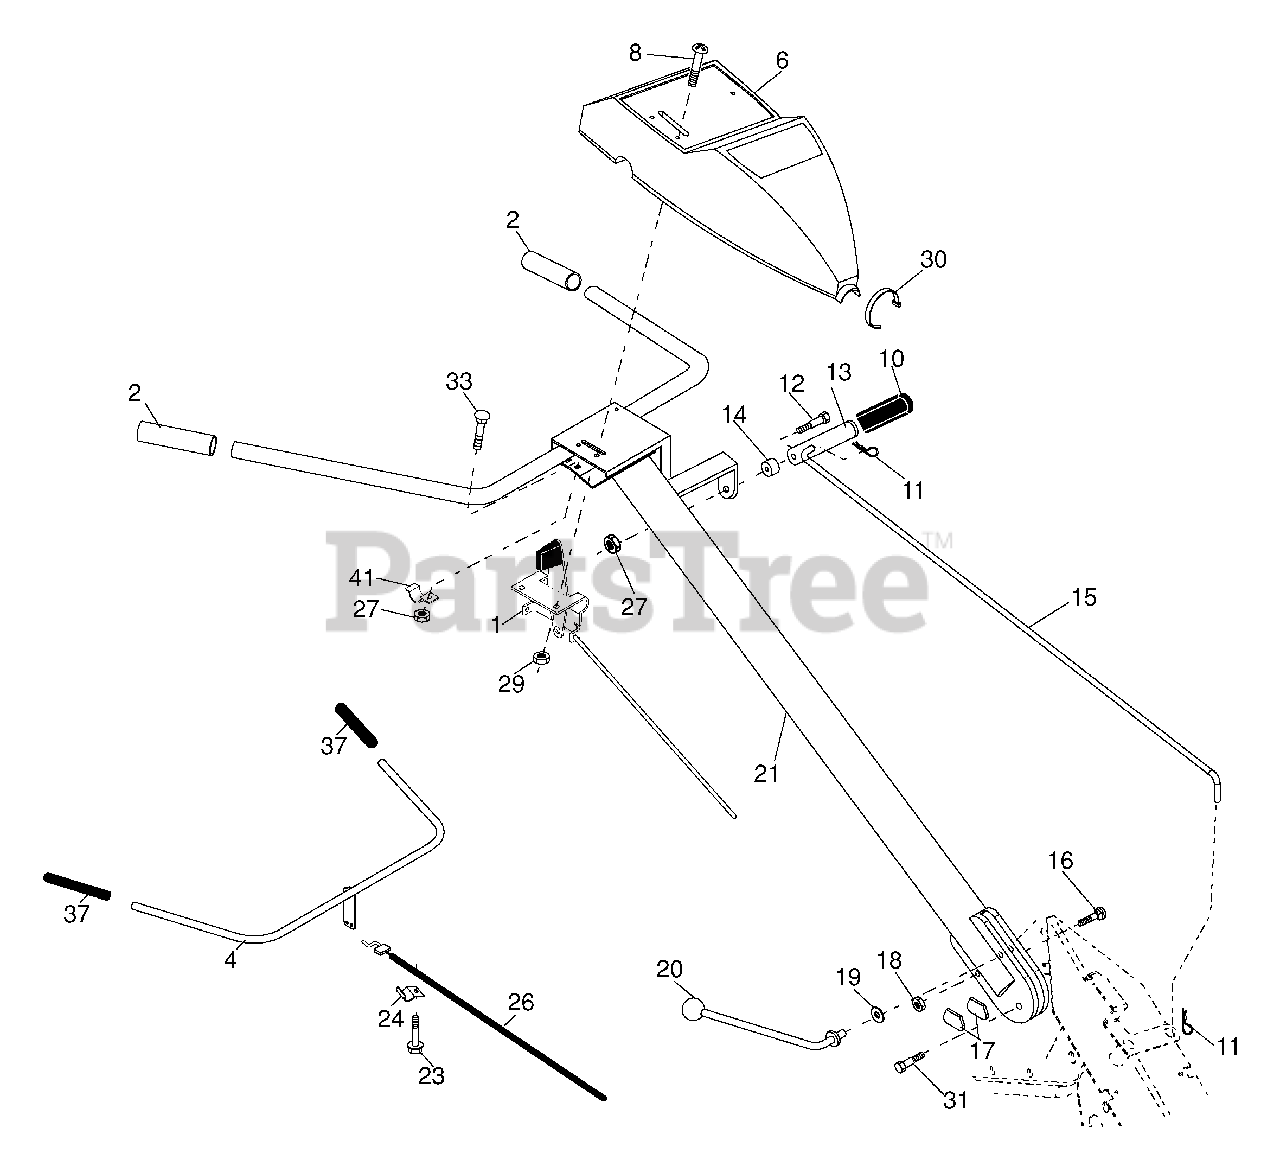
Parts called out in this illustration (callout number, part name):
1	Control, Throttle
2	Grip, Handle
4	Control Bar Assembly
6	Panel, Control
8	Screw, Truss Head #10-24 x 1/2
10	Grip, Handle
11	Clip, Hairpin
12	Bolt, Shoulder
13	Handle, Shift
14	Grommet, Rubber
15	Rod, Shift
16	Bolt, Carriage, Grade 5 3/8-16 x 1
17	Lock, Handle
18	Nut, Crownlock 3/8-16
19	Washer 13/32 x 1 x 11 Gauge
20	Lever, Lock, Handle
21	Handle
23	Screw, Slotted, Hex Washer Head #10-24 x 1/2
26	Cable, Clutch
27	Nut, Hex, Flanged 1/4-20
29	Nut, Hex, Keps #10-24
30	Tie, Cable
31	Bolt, Pivot
33	Bolt, Carriage 1/4-20 x 1/2
37	Grip, Control Bar
41	Clamp, Control Bar
